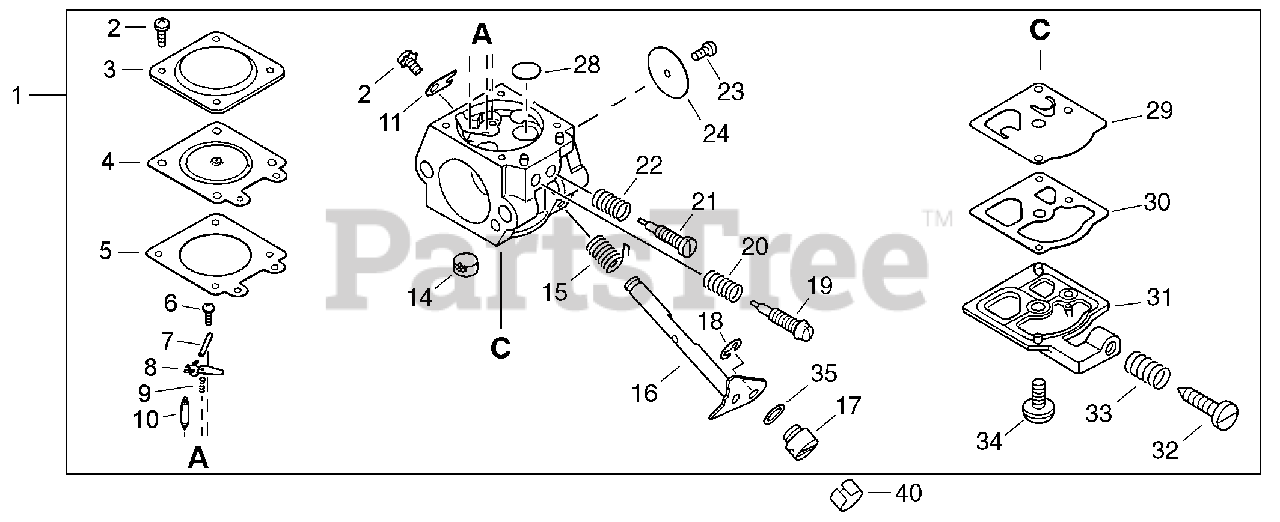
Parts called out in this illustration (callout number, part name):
1	CARBURETOR WT-120B
3	COVER, METERING
4	DIAPHRAGM, METERING
5	GASKET, METERING
6	SCREW, METERING LEVER PIN
7	PIN, METERING LEVER
8	LEVER, METERING
9	SPRING, METERING LEVER
10	VALVE, INLET NEEDLE
11	CLIP, THROTTLE SHAFT
14	STRAINER
15	SPRING, THROTTLE RETURN
16	SHAFT, THROTTLE
18	RING, RETAINING
19	NEEDLE - HIGH SPEED
21	NEEDLE - LOW SPEED
24	VALVE, THROTTLE
28	PLUG, WELCH
29	DIAPHRAGM, PUMP
30	GASKET, PUMP
31	COVER, PUMP
32	SCREW, IDLE ADJUST
33	SPRING, IDLE ADJUST
34	SCREW, PUMP COVER
40	CLIP
